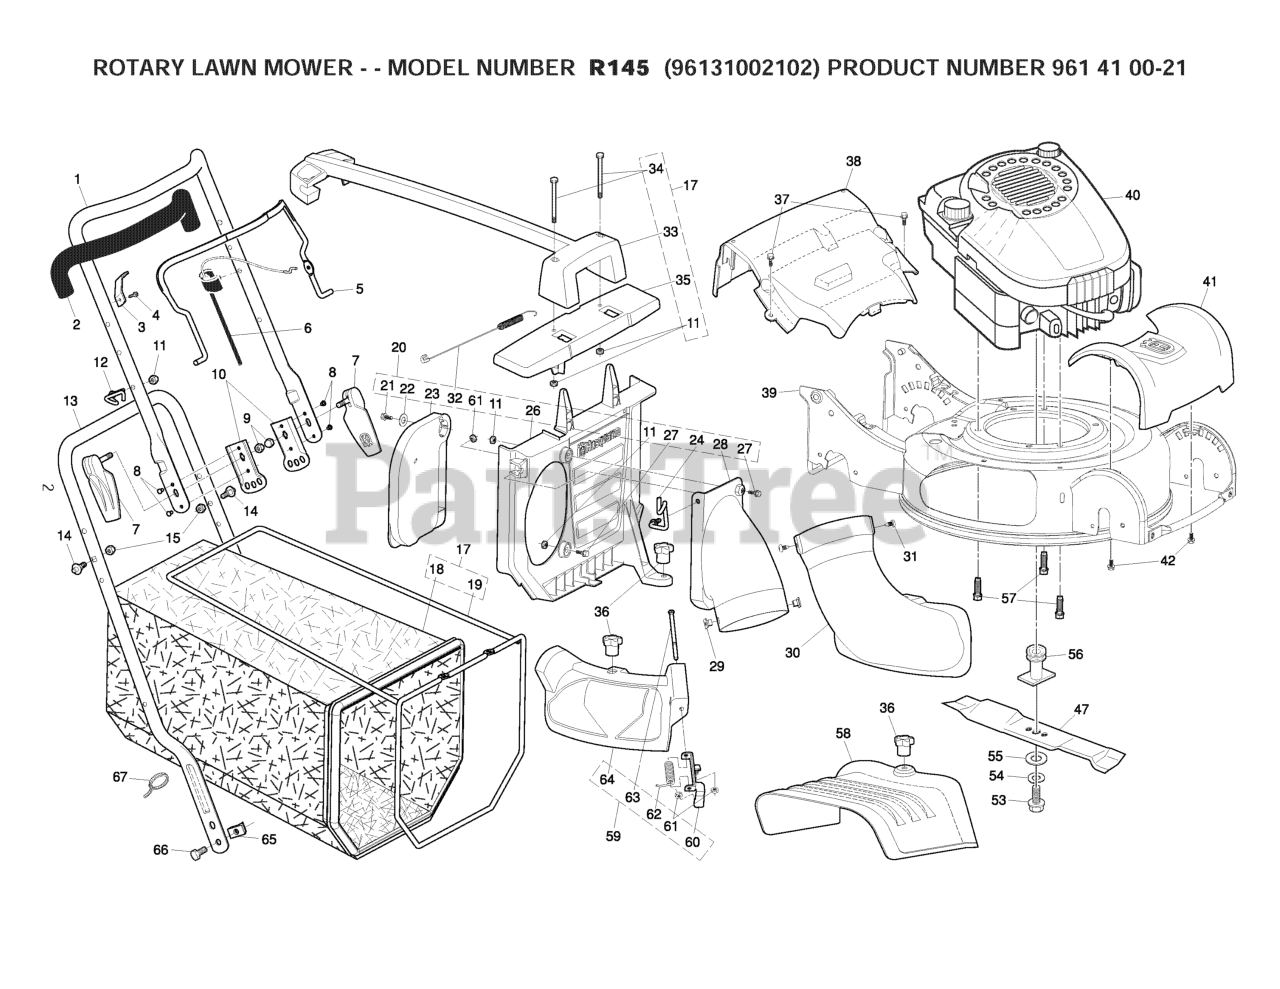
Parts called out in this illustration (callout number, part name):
2	GRIP, FOAM
3	BRACKET
5	BAIL CONTROL
6	CABLE.MZR.50.SNAP-IN
7	ASM.QUICK.RELEASE
9	Locknut, Hex 1/4-20
10	BRACKET.ADJ.3POS.GREY
11	NUT
12	RB GUIDE.ROPE.STD.BLK.ZIN WSL
14	STUD.QUICK.ADJUST
15	NUT.LOCK.5/16-18
22	WASHER
26	BOLT, SHOULDER
27	BOLT SHOULDER
31	SCREW T-30 1/4-20 X
36	KNOB.MULCH.DOOR
37	SCREW, HEX WASHER HEAD
42	SCREW.HWH.13-16-5.8.BZP
47	BLADE.SWEPT.WING.45CM.H.TREAT
53	BOLT.HD.HEAD.3/8-24X2.50 (2 2)
54	LOCKWASHER
55	WASHER,HARDEN
56	ADAPTER.BLADE.PUSH
57	BOLT 3/8-16X1-1/8
61	NUT.HEX.FLANGE.1/4
62	SPRING.MULCH.DOOR
63	ROD.HINGE.1/4"3.82"
64	DOOR.MULCH.GREY
67	TIE GUIDE
